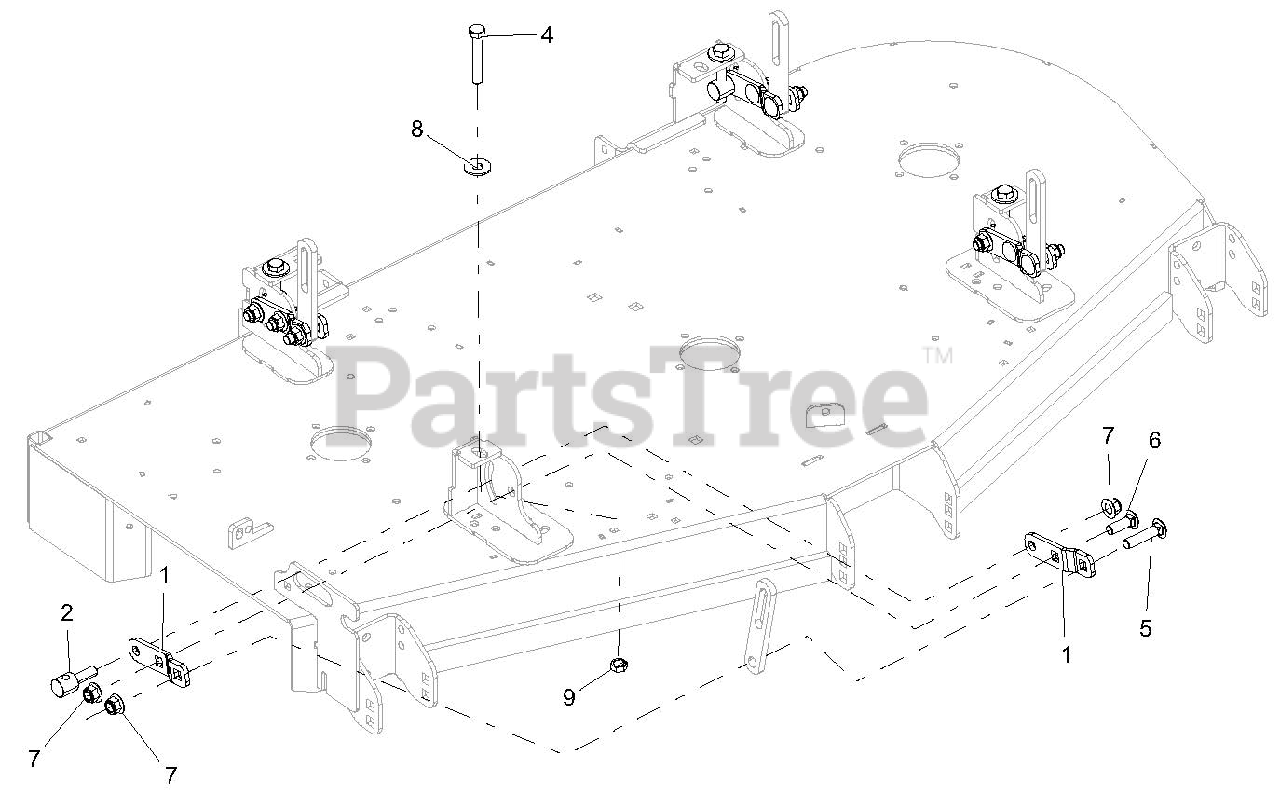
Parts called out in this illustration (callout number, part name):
1	BRKT, DECK LEVELING-BLACK
2	TRUNNION, .50-13
4	BLT-HEX .50-13X3.00 GR5 FTH YWZC
5	BLT-RDHDSQNK .50-13X2.25 G5Y
6	BLT-RDHDSQNK .50-13X1.50 G5 YWZC
7	NUT-LK-NYL-FLG .50-13 YWZC
8	WSHR-FL-STL.563X1.38X.109YWZC
9	NUT, JAM .500-13 YWZC
